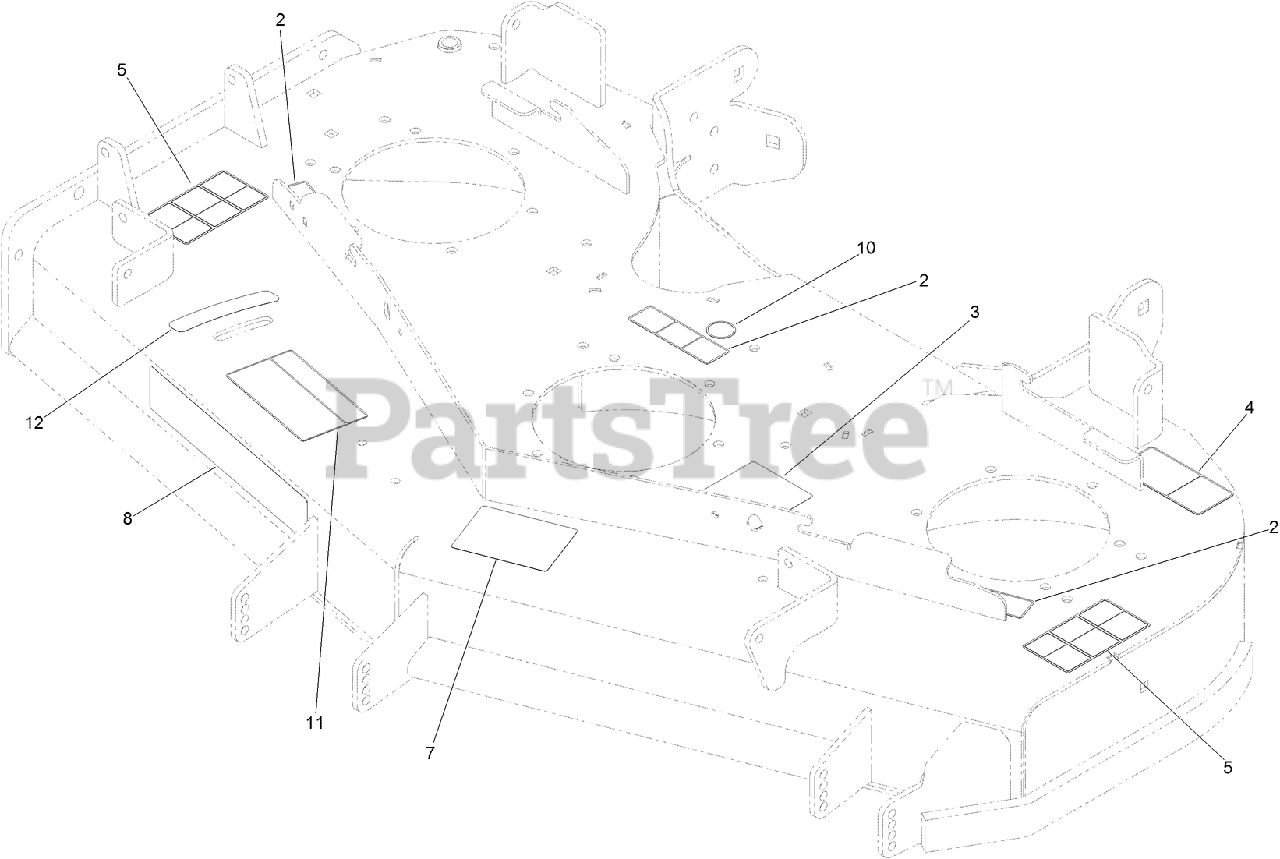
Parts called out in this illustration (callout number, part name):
2	DECAL-MISSING, COVER
3	DECAL-ROUTING, DECK BELT
4	DECAL-TORQUE, BLADE BOLT
5	DECAL-DANGER
7	DECAL-SCALP, ANTI
10	DECAL-GREASE
11	DECAL-ADJUSTMENT, BAFFLE
12	DECAL-SETTING, BAFFLE
